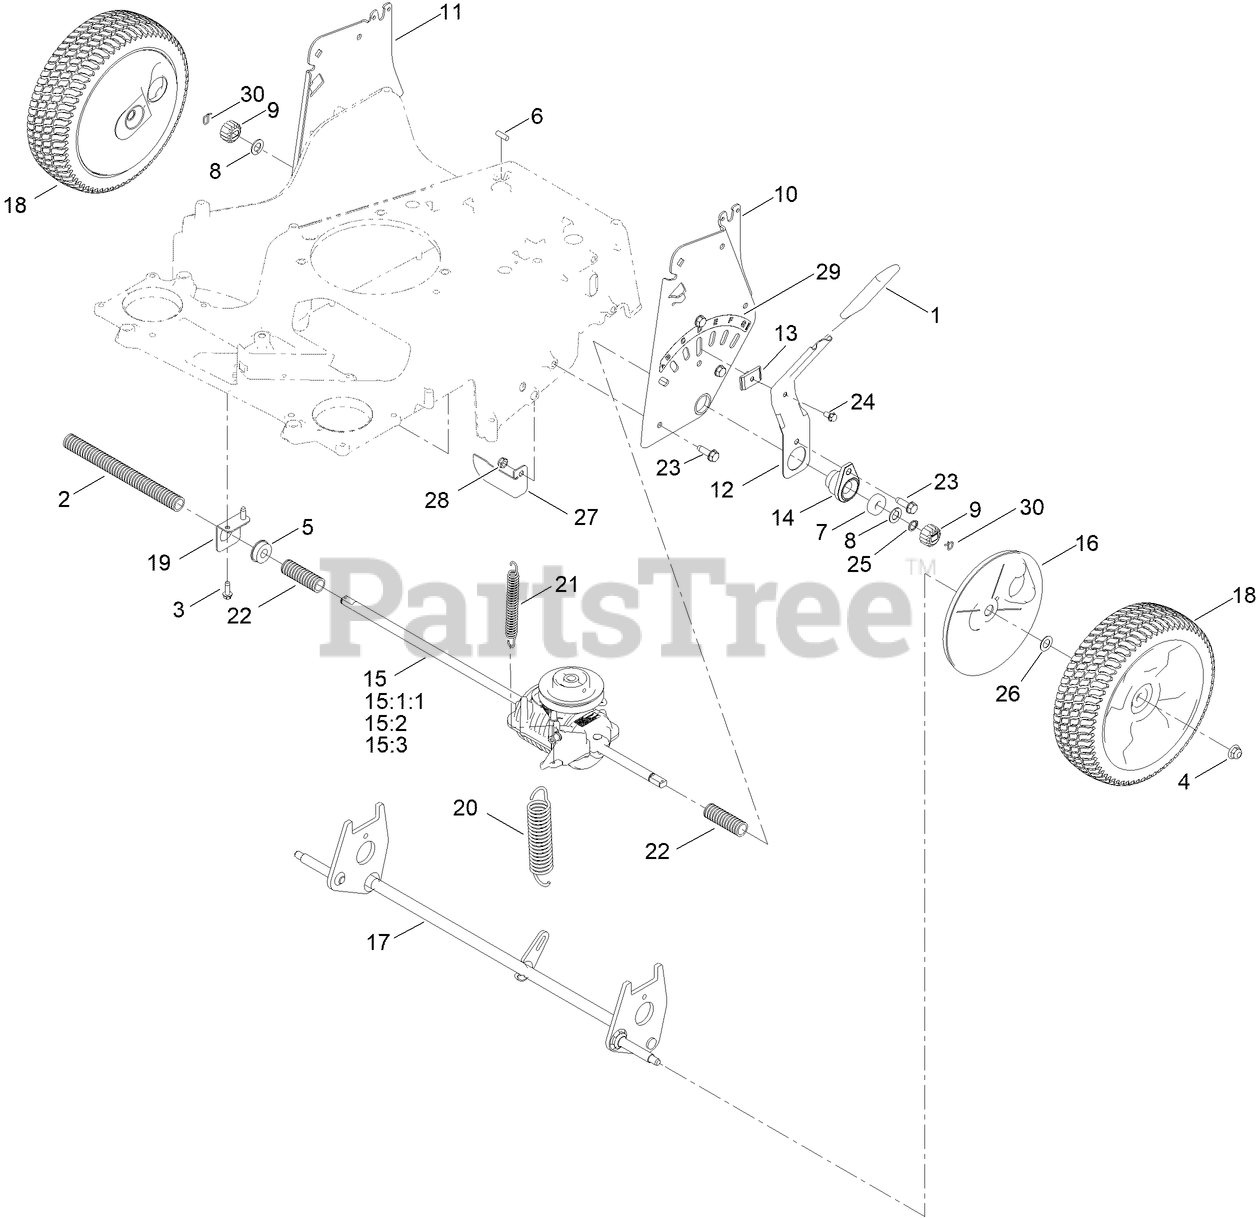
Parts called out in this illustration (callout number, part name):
1	GRIP-LEVER, LIFT
2	CONDUIT-CONVOLUTED
3	SCREW-HWHTF
4	NUT-HF, NI
5	BEARING-BALL
6	PIN-STOP
7	BEARING-BALL
8	WASHER-THRUST
9	GEAR-PINION, 15T
10	PLATE-HOC, LH
11	PLATE-HOC, RH
12	ARM-SPRING
13	KEY-SPRINGARM
14	RETAINER-BEARING
15	TRANSMISSION KIT
15:1:1	TRANSMISSION PULLEY KIT
15:2	PIN-SNAP
15:3	RING-RETAINING
16	COVER-GEAR
17	REAR AXLE ASM
18	10 INCH WHEEL GEAR ASM
19	MOUNT-BEARING
20	SPRING-EXTENSION
21	SPRING-EXTENSION
22	CONDUIT-CONVOLUTED
23	SCREW-THD ROLL, HWH
24	SCREW-HWH
25	RING-RETAINING
26	WASHER-PLAIN
27	BRACKET-STOP
28	NUT-LOCK, NI
29	DECAL-HOC, REAR
30	PIN-SNAP
